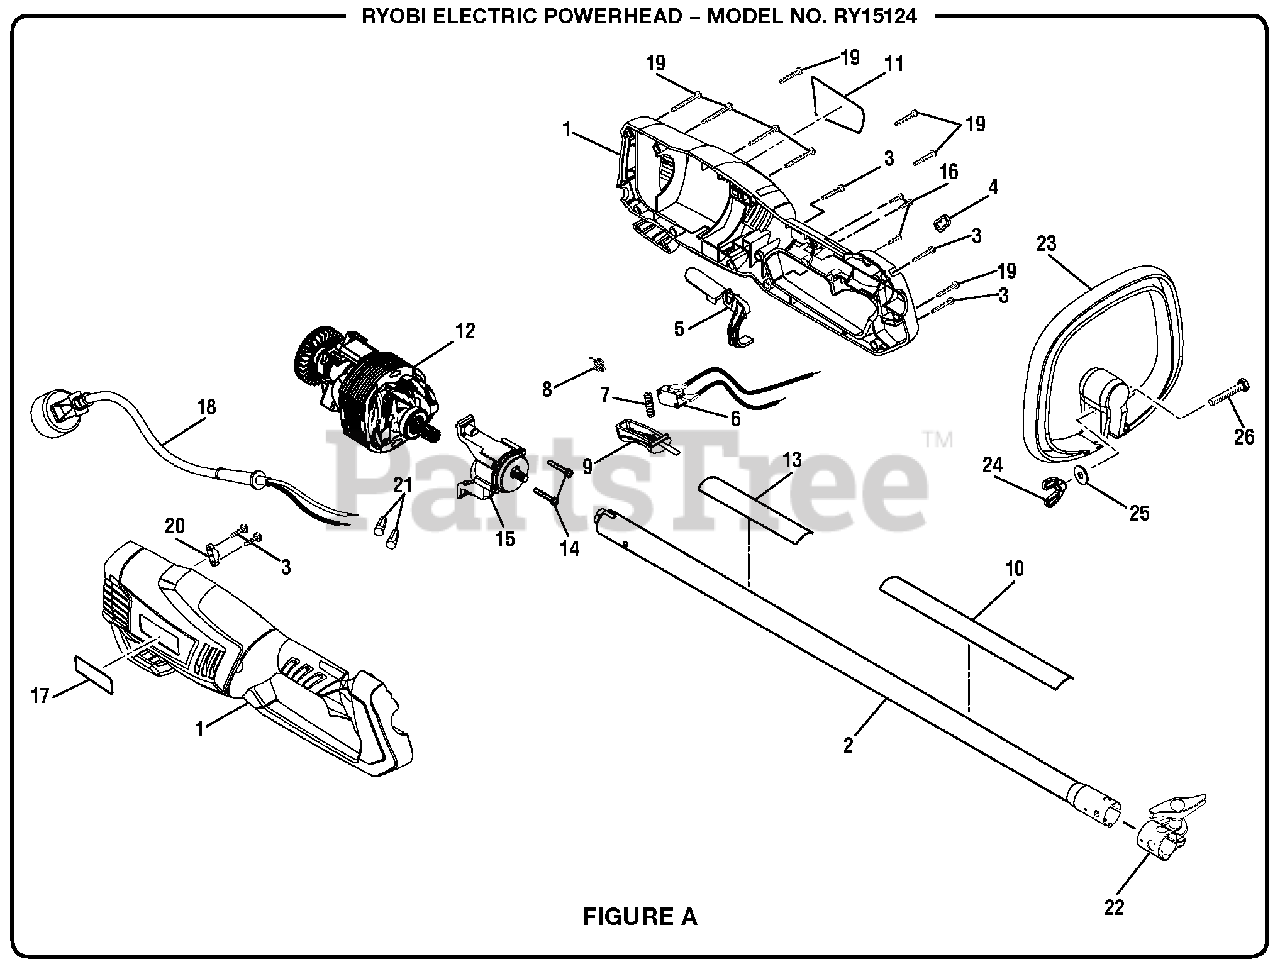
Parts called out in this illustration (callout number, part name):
1	Housing Assembly
2	Boom Assembly
3	Screw (M4 x 14 mm)
5	Lock-Out Lever
6	Switch Assembly w/Leads
7	Compression Spring
8	Torsion Spring
9	Switch Trigger
10	Warning Label (French)
11	Data Label/Warning Label (English and Spanish)
12	Motor Assembly
13	Icon Strip Label
15	Gear Assembly
16	Screw (M3 x 12 mm)
17	Logo Label
18	Power Cord Assembly
19	Screw (M4 x 16 mm)
22	Boom Clamp Assembly
23	Front Handle Assembly
24	Wing Nut (1/4-20)
25	Washer (1/4 in.)
26	Bolt (1/4-20 x 40 mm)
